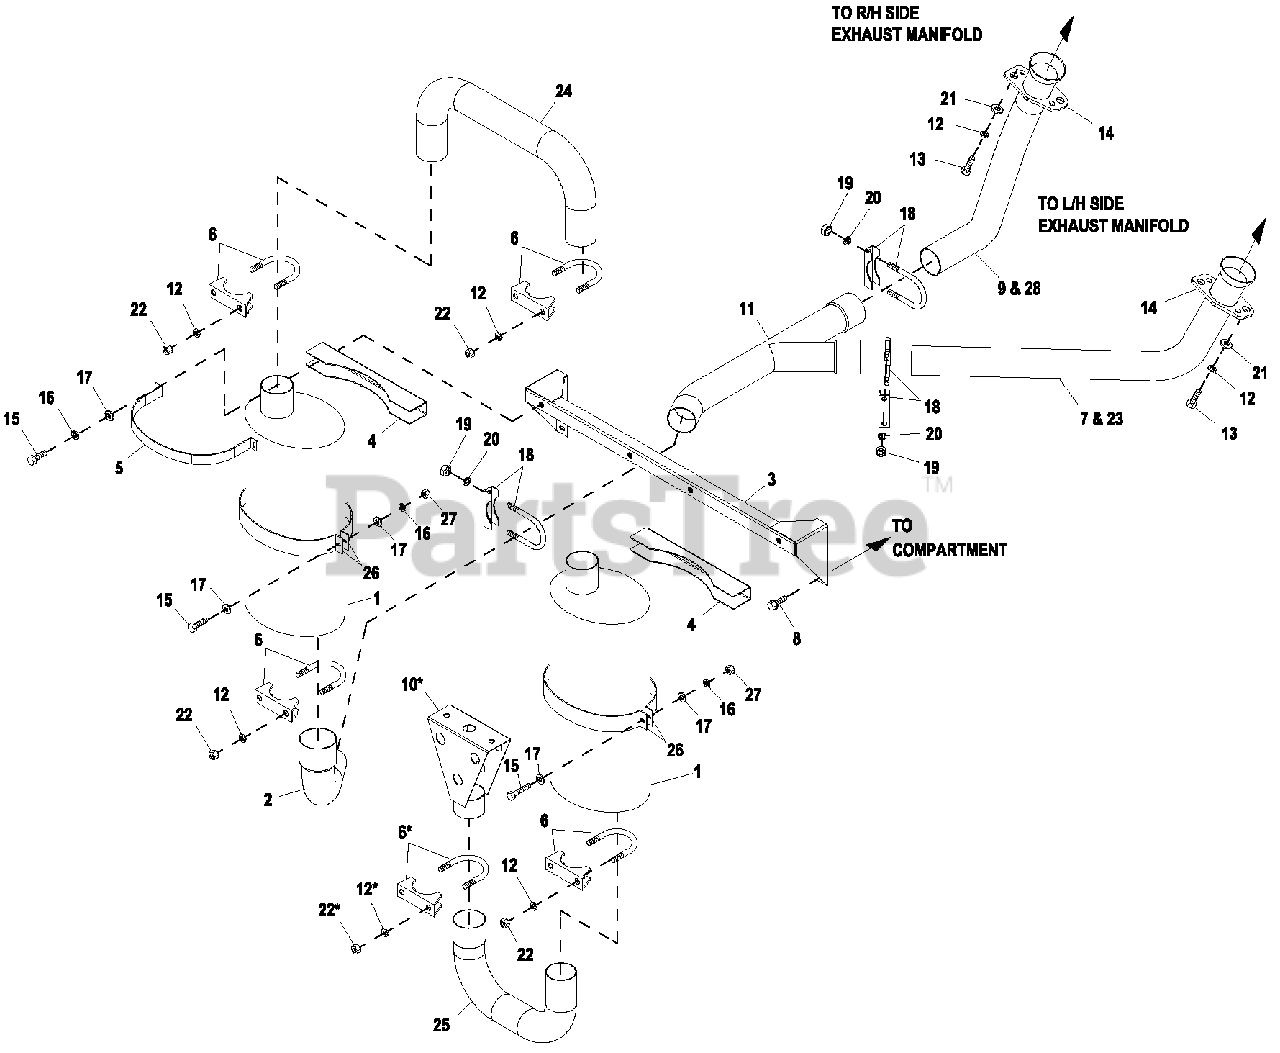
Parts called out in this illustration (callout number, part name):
1	MUFFLER 7" X 9" X 18-1/2" 2" IN/OUT
2	EXHAUST ELBOW 2"ID X 2-1/2"OD
3	BRAC KET MUFFLER
4	MUFFLER BRAC KET STIFFENER
5	MUFFLER STRAP
6	BOLT U 3/8-16X2.62
7	PIPE EXHAUST LEFT 2"OD
8	SCREW THF M6-1 X 16 N WA Z/JS
9	PIPE EXHAUST RIGHT 2"OD
10	DIFFUSER EXHAUST WELDMENT
11	Y-PIPE EXHAUST 2"OD 4.2L G3
12	WASHER LOC K 3/8 SS
13	SCREW HHC M10-1.5 X 45 SS FTH
14	EXHAUST FLANGE 2" PIPE
15	SCREW HHC M6-1.0 X 35 G8.8 BL K
16	WASHER LOCK M6-1/4
17	WASHER FLAT 1/4-M6 ZINC
18	BOLT U 5/16-18X2.25
19	NUT HEX 5/16-18 STEEL
20	WASHER LOC K M8 SS
21	WASHER FLAT 3/8 SS
22	NUT HEX 3/8-16 STEEL
24	PIPE EXHAUST CROSSOVER
25	PIPE EXHAUST MUFFLER OUT
26	MUFFLER STRAP UPPER/LOWER
27	NUT HEX M6X1.0 G8 YEL CHR
